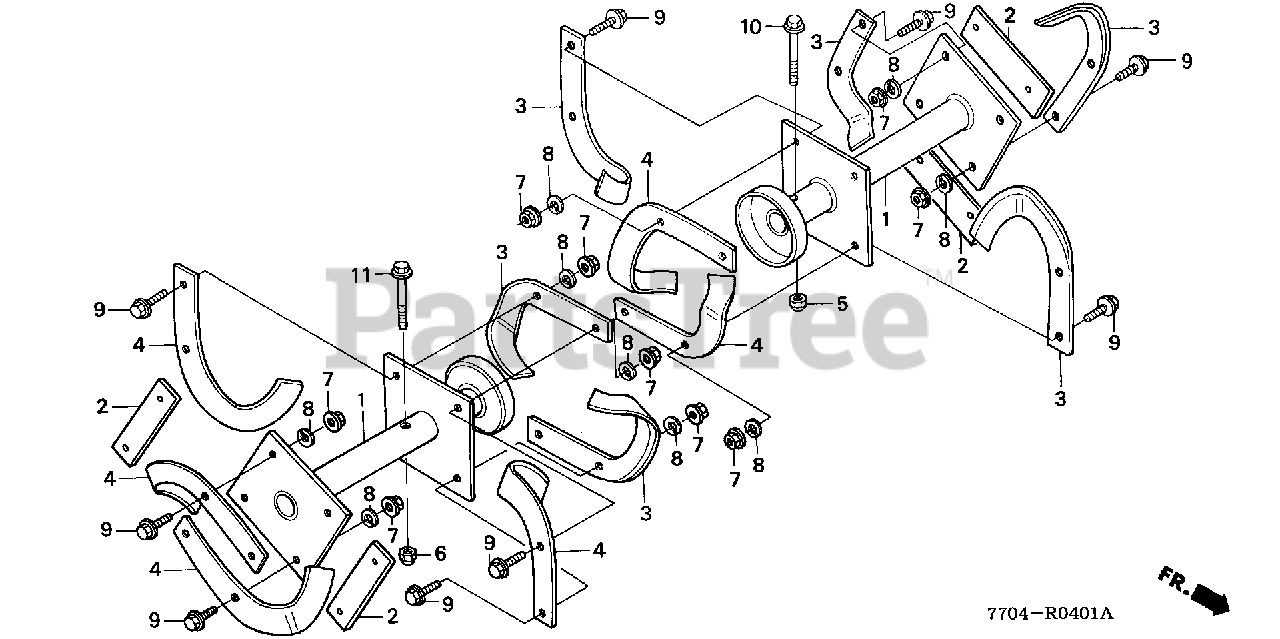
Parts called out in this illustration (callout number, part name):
1	SHAFT, ROTARY PIPE
2	PLATE, TINE
3	TINE A, ROTARY
4	TINE B, ROTARY
5	NUT, SELF-LOCK (8MM)
6	NUT, SELF-LOCK (10MM)
7	NUT, FLANGE (10MM)
8	WASHER, SPRING (10MM)
9	BOLT, FLANGE (10X30)
10	BOLT, FLANGE (8X50)
11	BOLT, FLANGE (10X50)
